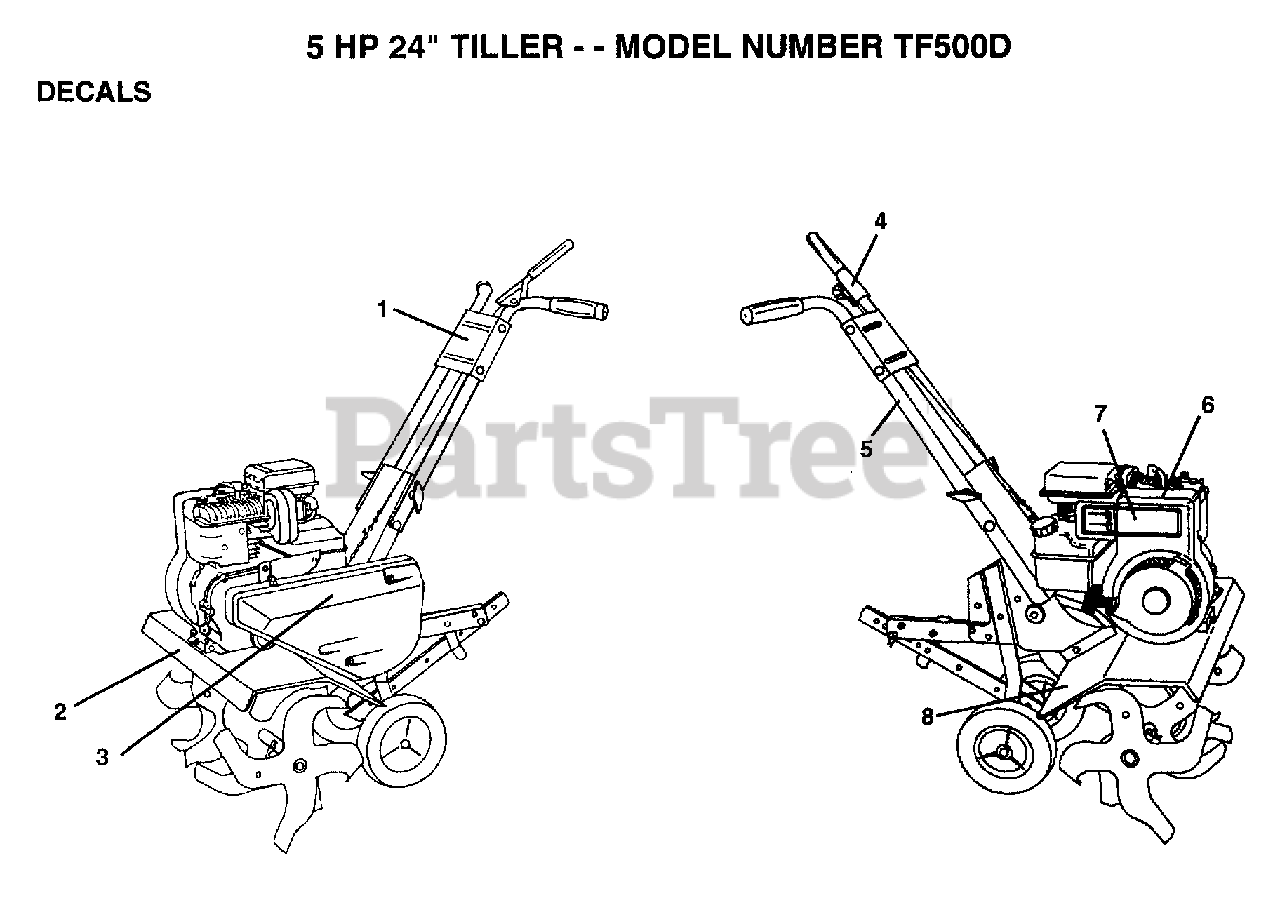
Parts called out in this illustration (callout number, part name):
1	DECAL, LOGO
2	DECAL TINE SHIELD
4	DECAL TI
5	DECAL TI
8	DECAL TI
